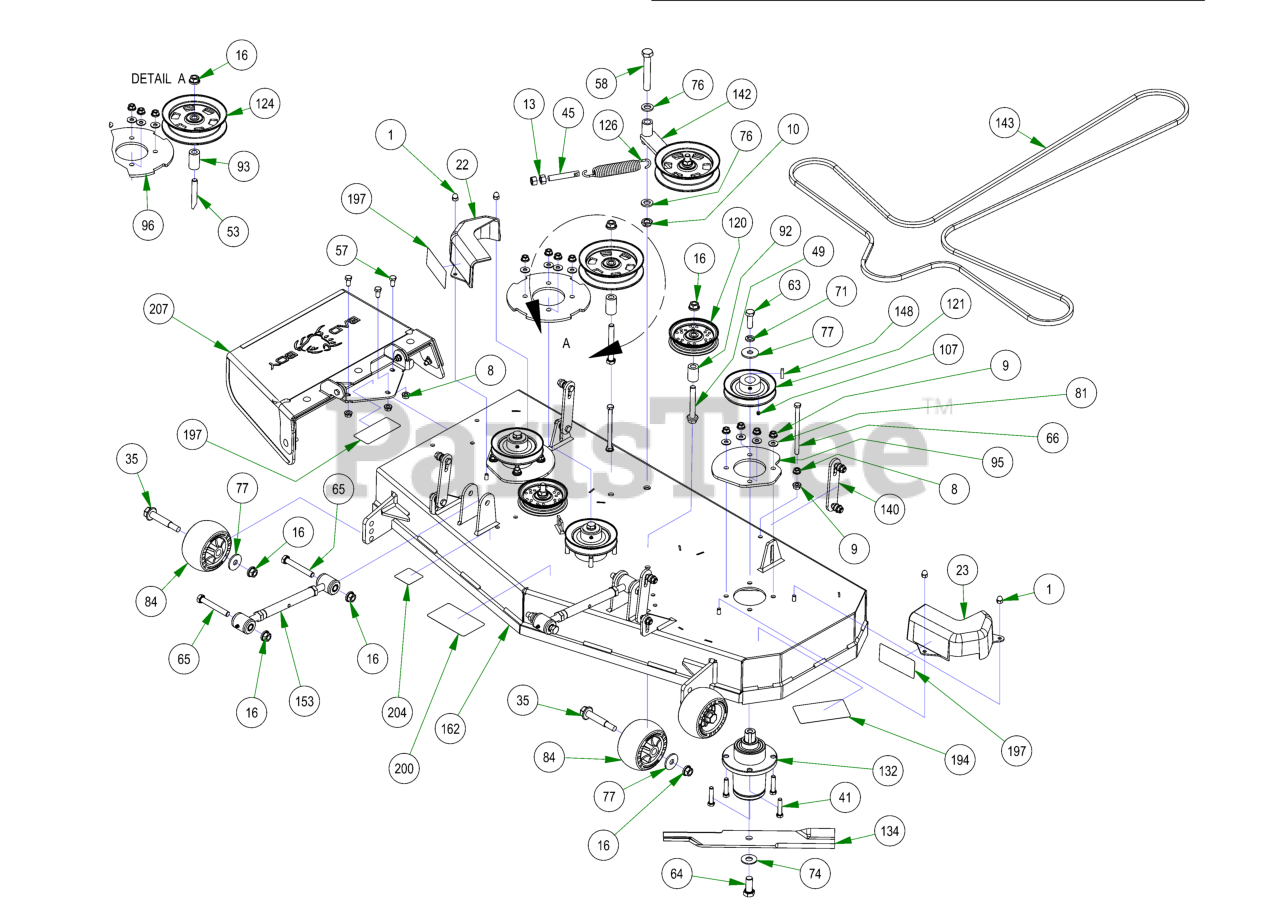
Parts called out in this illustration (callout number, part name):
1	5/16-18 ACORN NUT HIGH-CROWN ZC
8	3/8-16 HEX SERRATED FLANGE NUT HARD/ZINC
9	3/8-16 NYLON INSERT FLANGE LOCKNUT (GR.F) ZINC
10	5/8-11 NYLON INSERT JAM LOCKNUT ZINC
13	1/2-13 HEX NUT ZINC
16	1/2-13 NYLON INSERT FLANGE LOCKNUT ZINC
22	pulley cover chute side
23	pulley cover non-chute side
35	Deck Wheel Bolt
41	3/8-16 X 1-3/4 HEX C/S (GR.5) ZC
45	All Thread
49	1/2-13 X 3-1/2 HEX FLANGE BOLT (GR.8) ZINC
53	1/2-13 X 4 HEX CAP SCREW (GR.8) ZINC YELLOW
57	3/8-16 X 3/4 HEX CAP SCREW (GR.5) ZINC
58	5/8-11 X 4 HEX CAP SCREW (GR.8) ZINC YELLOW
63	1/2-20 X 1-1/2 HEX CAP SCREW (GR.5) ZINC
64	5/8-18 X 1-1/2 HEX CAP SCREW (GR.8) ZINC YELLOW
65	1/2-13 X 3-1/2 HEX CAP SCREW (GR.5) ZINC
66	3/8-16 X 5-1/2 HEX CAP SCREW (GR.5) ZINC
71	1/2 SPLIT LOCKWASHER (GR.8) ZINC/YELLOW
74	5/8 USS FLAT WASHER (1-3/4" OD) GR.8 ZINC YELLOW
76	.635 ID X 1.120 OD X .140 THICK FLAT WASHER NYLON
77	1/2 BELLEVILLE WASHER (1-5/8 OD X .140 THK) ZINC
81	5/16 USS FLAT WASHER (7/8 OD) ZINC
84	Deck Wheel
92	.502 ID X .750 OD X 1.500 Long Spacer
93	1 3/4" Pulley Spacer
95	42&48 Deck Spindle Support Plate
96	Deck Spindle Support Plate
107	5/16-24 X 1/4 SOCKET SET SCREW (CUP PT) PLAIN
120	4 3/4 Idler Pulley - ABFI-76
121	5" Spindle Deck Pulley
124	5-3/4 Idler Pulley
126	Deck Idler Spring
132	Spindle Assembly
134	48" ZT/Mav/Compact Outlaw Blade with Fusion
140	Deck Hanger Assembly
142	2017 MZ/ZT Deck Idler Assembly
143	B147 Deck Belt
148	1/4 X 1 SQ MACHINERY KEY 1018 STL PLN
153	2018 Maverick Turnbuckle (Top Link)
162	2023 48" x 5" Deck
194	2018 48" Deck Decal
197	Danger Decal-Spindle/Discharge
200	Deck Belt Route Decal
204	Deck Impact Patent Decal 9591803
207	ZT Chute Assembly
